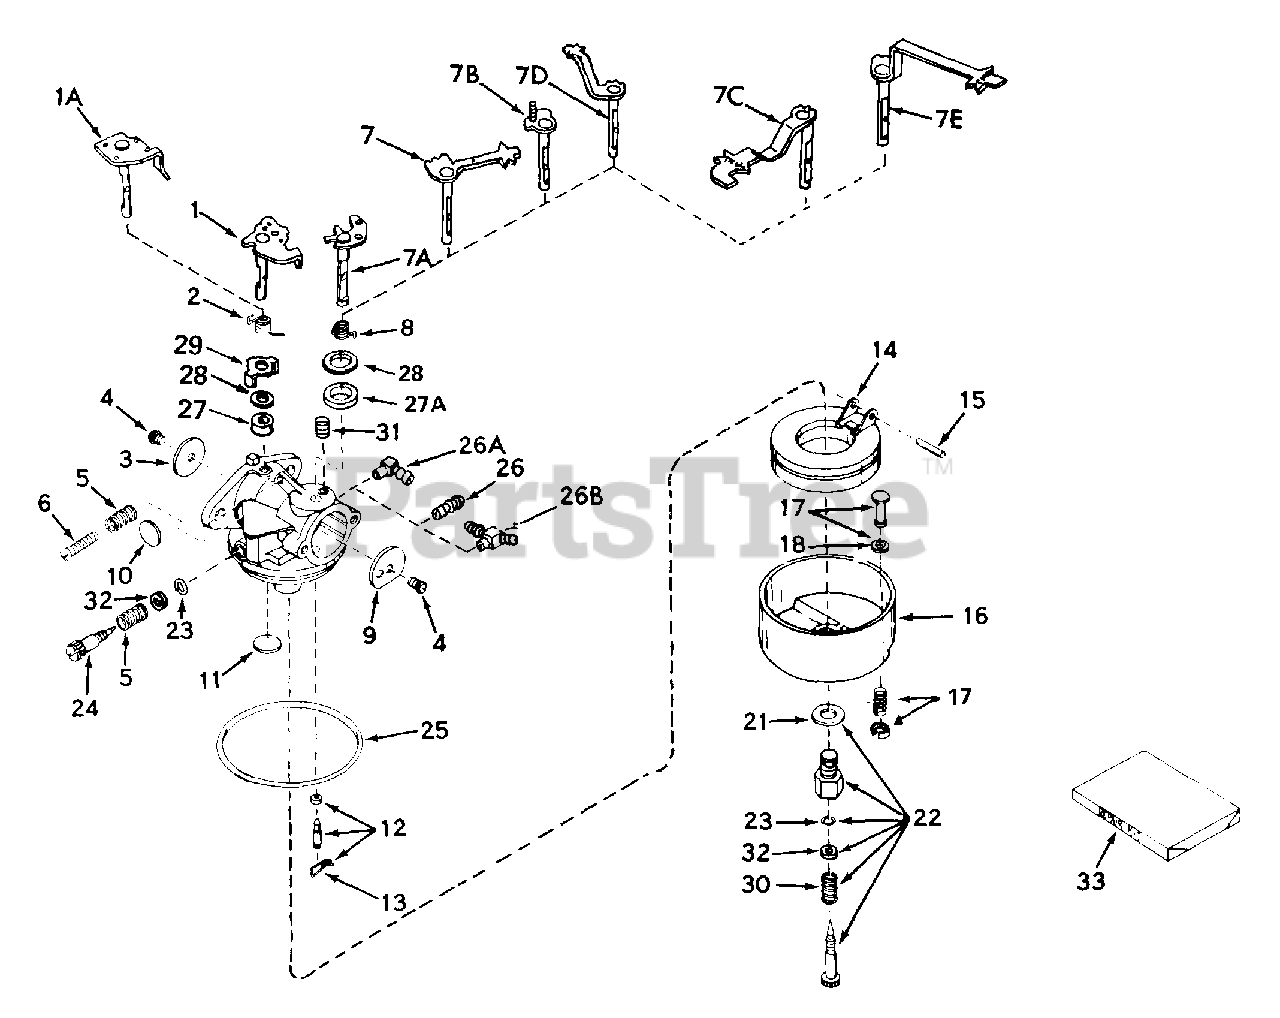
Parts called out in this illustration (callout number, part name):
1	"Shaft & Lever Assy., Throttle
2	Spring, Throttle return
3	Shutter, Throttle
4	Screw, Throttle & Choke shutter
5	Spring, Regulating screw
6	Screw, Idle regulating
7A	Shaft & Lever Assy., Choke
8	S-pring, Choke return
9	Shutter. Choke
10	Plug, Welch
11	Plug, Welch
12	Inlet Needle, Seat & Clip Assy.
13	Clip, Inlet needle
14	Float, Carburetor
15	Shaft, Float
16	Bowl, Float
21	Gasket, Bowl-to-body
22	Adj. Screw Assy.,
23	"O" Ring, Adj. screw
24	Screw, Idle adj.
25	Gasket, Bowl-to-body
26B	Fitting, Fuel inlet
27	Seal, Dust
27A	Seal, Dust
28	Washer, Dust seal
29	Retainer, Dust seal
30	Spring, Main adj. screw
33	Repair Kit
